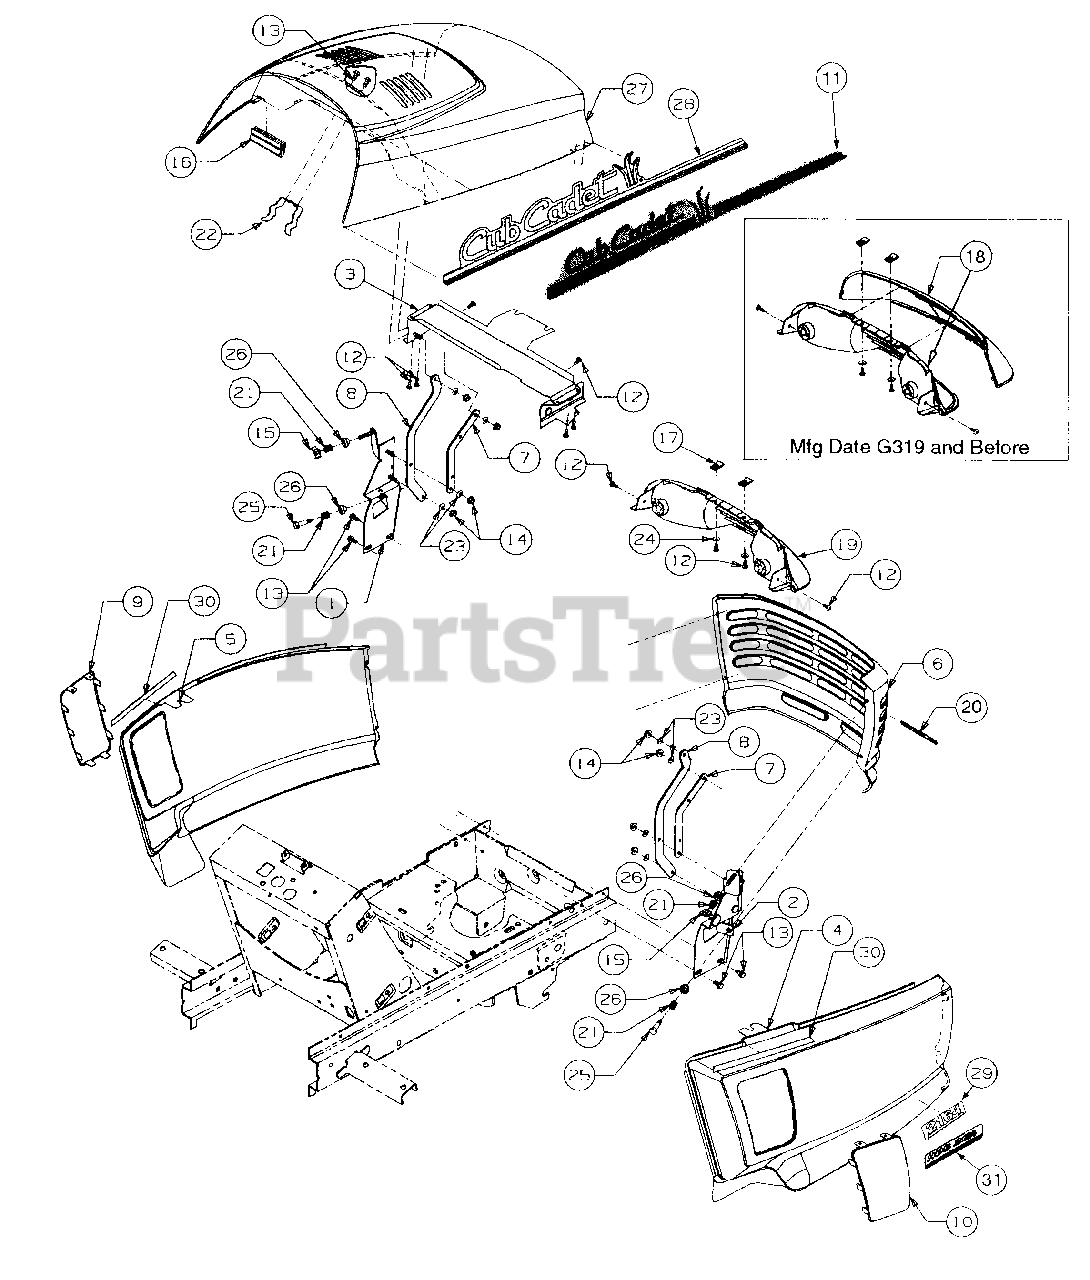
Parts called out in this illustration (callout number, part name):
1	Bracket, Grille LH
2	Bracket, Grille RH
3	Bracket, Upper Hood
4	Panel, RH Side
5	Panel, LH Side
8	Link, Long Hood
9	Screen, LH Panel
10	Screen, RH Panel
11	Graphic, Hood w/MTD Logo RH
12	Screw, Truss Mach Tapp, #10 x .50
13	Screw, Hex Wash Hd Tapp, 1/4 x .50
14	Nut, Hex Flange Lock, 1/4-20
15	Nut, Wing, 1/4-20
16	Seal, Heat Baffle
17	Nut, U-Type Speed, #10
18	Headlight Assy
19	Headlight Assy
20	Graphic, Warning HOT
21	Spring, Compression, .50 OD x .50 Lg
22	Spring, Hood Latch
23	Washer, Spring, .265 x .562 x .025
24	Washer, Flat, .218 x .62 x .063
25	Bolt, Shoulder, .31 Dia x .75 Lg
26	Bushing, Tapered
27	Hood, Series 2000
28	Graphic, Hood RH
29	Graphic, 2164
30	Strip, Protective
31	Graphic, HGS 2164
